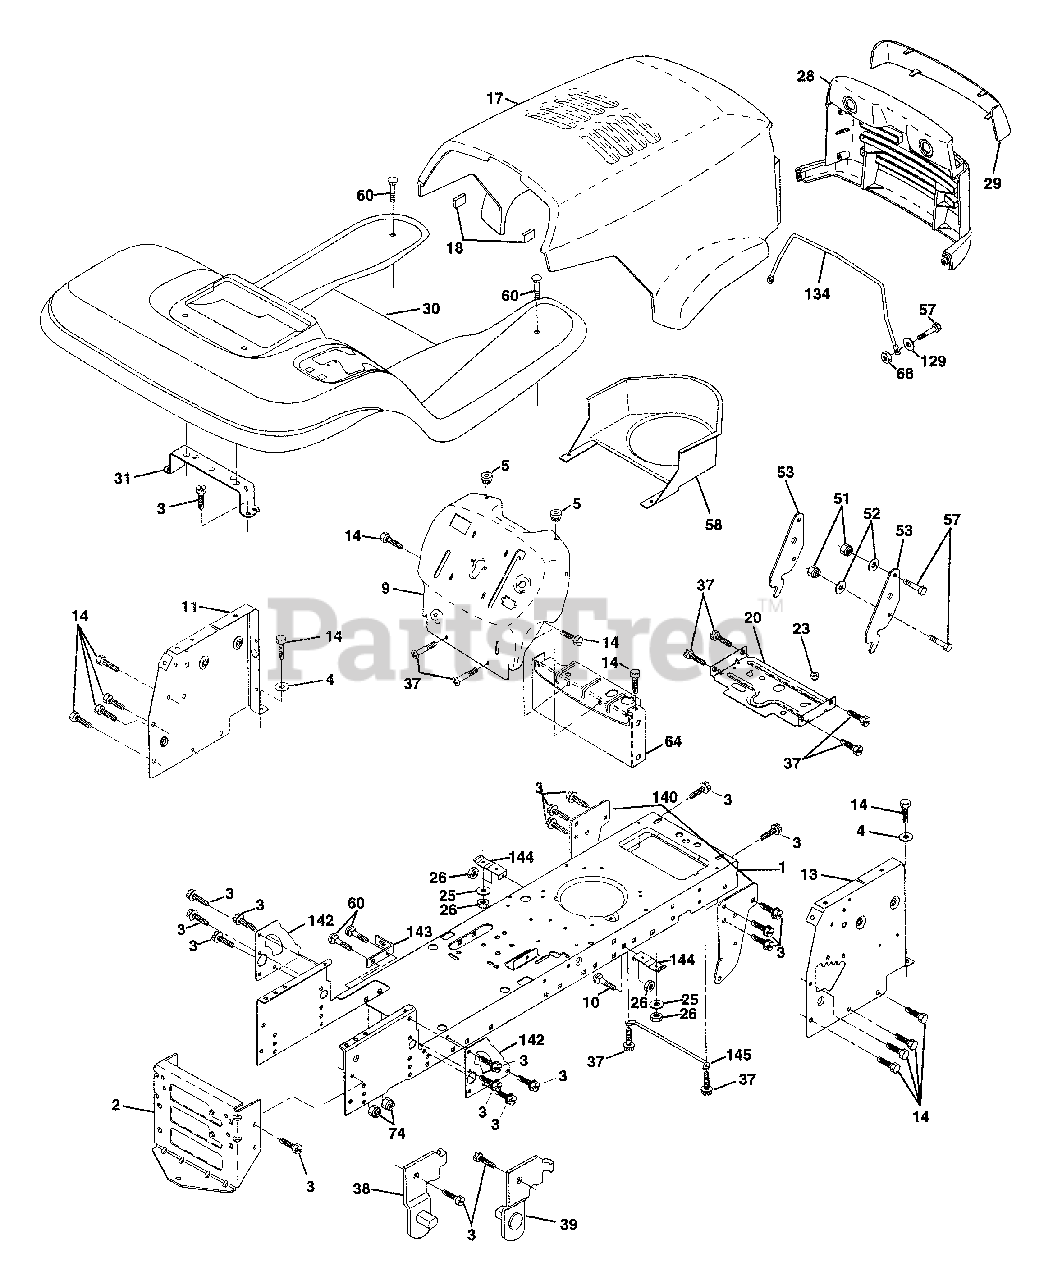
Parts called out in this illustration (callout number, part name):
1	Chassis Weldment
2	Drawbar, Stretch
3	Screw Thdrol 3/8-16x3/4 Ty-tt
4	Washer 13/32 x 3/4 x 16 Ga.
5	Bumper Hood/Dash
9	Dash P/L M, Slkscr Mech Na N/HM
10	Bolt Carriage 3/8-16 x 1
11	Panel Dash Lh
13	Panel Dash Rh
14	Screw Thdrol 3/8-16x1/2 Ty-tt
17	Hood LT/PL Husqvarna
18	Bumper Hood
20	Plate Mtg Battery Fuel Tank Fr
25	Washer 13/32 X 13/16 X 12 Ga
26	Nut Lock Hex W/Ins 3/8-16 Unc
28	Grille LT/PL Husqvarna
29	Lens LT/PL Husqvarna
30	Fender Footrest STLT Pnt
31	Bracket Support Fender
37	Screw Thdrol 6/16-18 x 1/2 TYT
38	Bracket, Asm. Pivot, L.H., Mower Rear
39	Bracket, Asm. Pivot, R.H., Mower Rear
51	Nut Lock Hex W/Ins 1/4-20
52	Washer 9/32 x 7/8 x 16 Ga.
53	Bracket Pnt. Pick off LT/PL Husqvarna
57	Bolt Hex 1 /4-20 x 3/4
58	Air Duct Engine P/L
60	Bolt Rdhd Sqnk 3/8-16unc x 3/4
64	Dash Lower STLT
68	Nut Keps Hex 1/4-20 Unc
74	Nut Crownlock 3/8-16 UNC
129	Washer 9/32 x 5/8 x 16 Ga.
134	Rod Support Hood LT/PL Husq.
140	Bracket Suspension Front
142	Plate Reinforcement STLT
143	Bracket Swaybar Chassis
144	Bracket Pnt Footrest STLT
145	Rod Pivot Chassis/Hood
